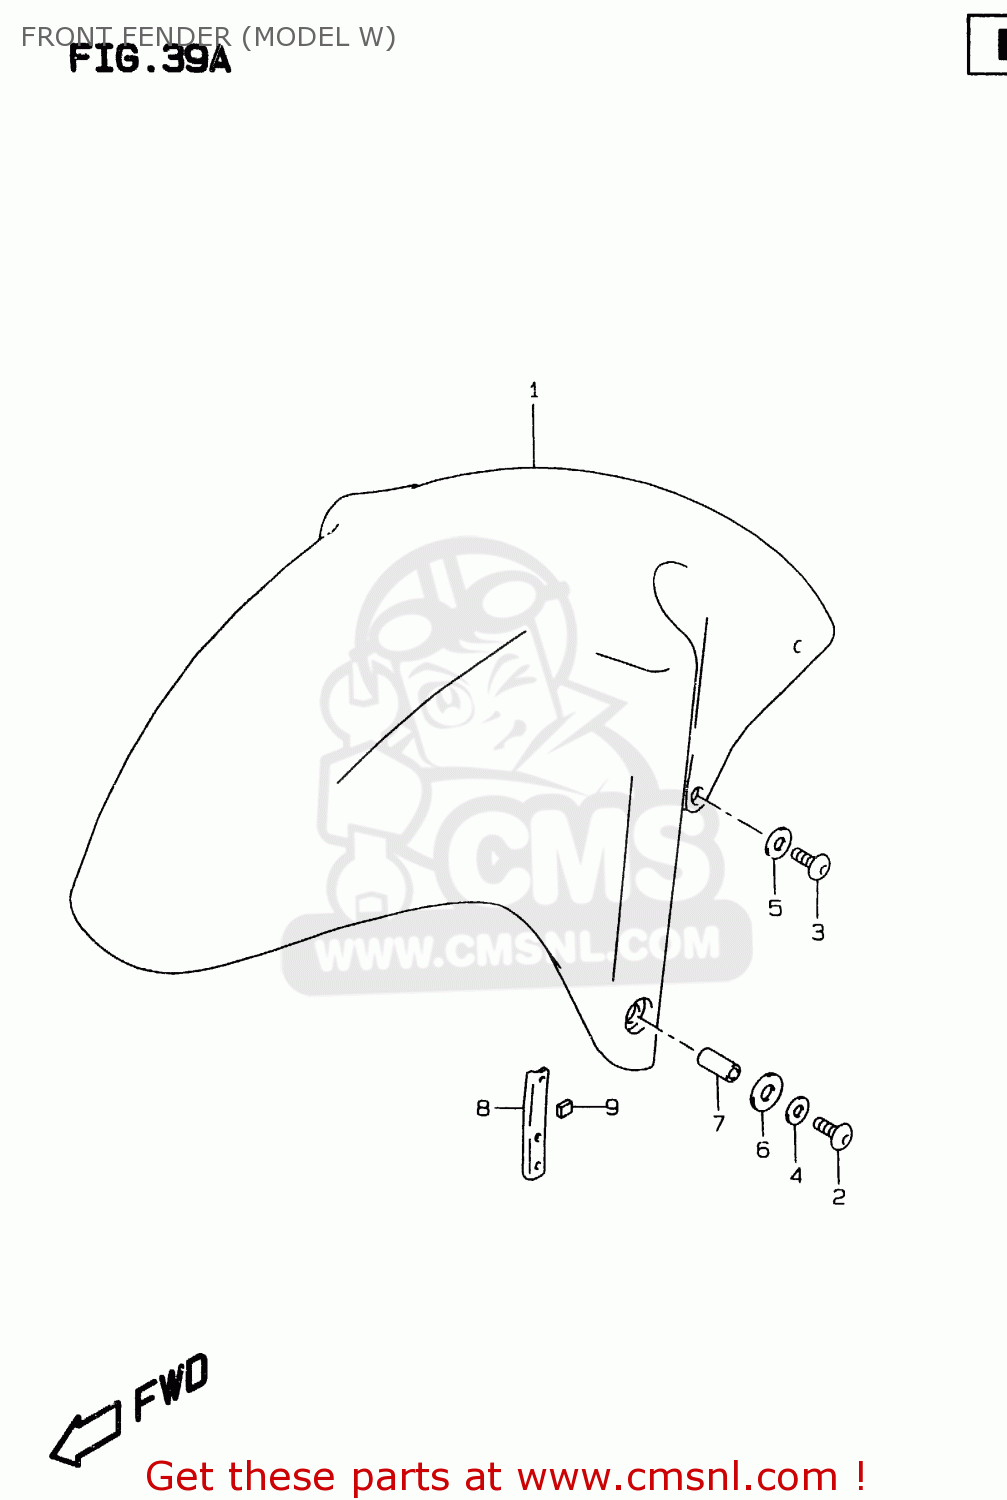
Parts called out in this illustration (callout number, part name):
1	FENDER,FR
2	SCREW(6X20)
3	SCREW(6X16)
4	WASHER(6.5X16X1.2)
5	WASHER(6.3X16X1.5)
6	WASHER,FR FENDER FR NO.2
7	SPACER(6.5X9X6.7)
8	PLATE,FRONT FENDER
9	CUSHION
